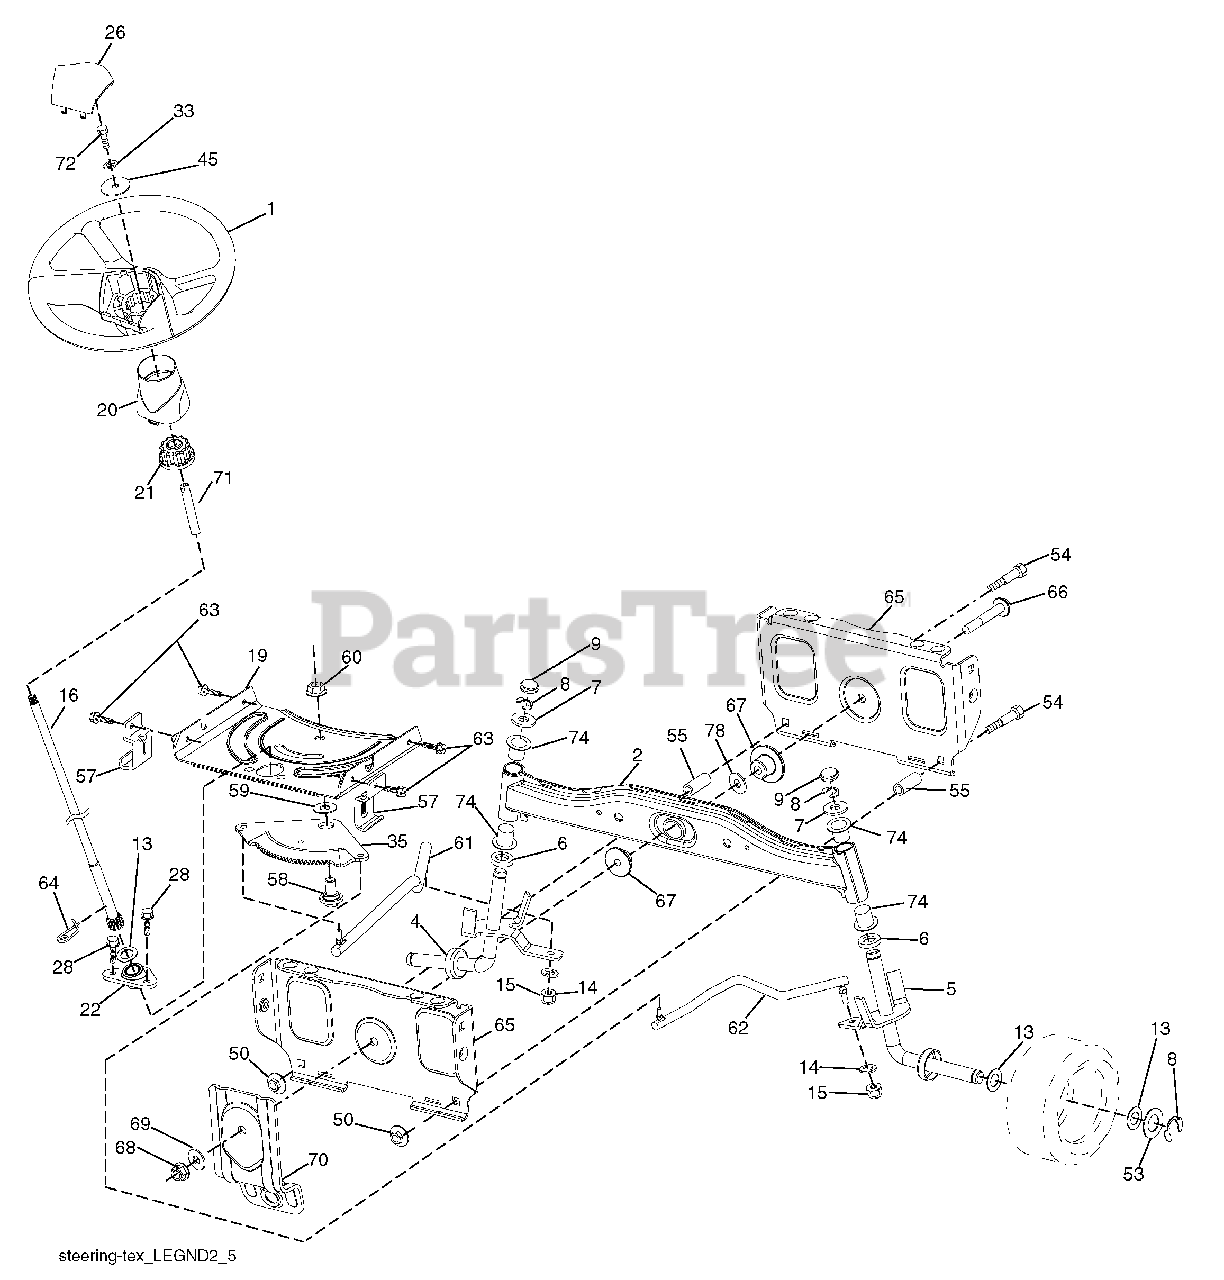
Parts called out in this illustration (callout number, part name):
1	Wheel, Steering
2	Axle Asm. Front
4	Spindle Asm. LH
5	Spindle Asm. RH
6	Bearing, Race Thrust Harden
7	Washer 25/32 x 1-5/8 x 16 Ga.
8	Ring, Clip #T5304-75
9	Cap, Spindle
13	Washer 25/32 x 1-1/4 x 16 Ga.
14	Washer, Lock Hvy. Hlcl. Spr. 3/8
15	Nut, Crown Lock 3/8-24 unf
16	Shaft Steering
19	Plate Steering
20	Boot, Steering
21	Adapter, Wheel Steering
22	Bushing, Strg. Blk.
26	Insert, Wheel Steering
28	Screw 3/8-16 x 3/4
35	Gear, Sector Plate
45	Washer 11/32 ID x 2-3/8 OD x 12 Ga.
50	Nut Lock 3/8-16 unc
51	Nut Hex Jam Toplock 1/2-20 unf
53	Washer Hardened .793 x 1.637 x .060
54	Bolt Hex 3/8-16 unc x 2-1/4
55	Spacer Brace Axle
57	Bracket Upstop
58	Bolt Shoulder Sector Pivot CFM
59	Washer Thrust Sector Steering
60	Nut Flange Lock 5/8-11
61	Draglink LH
62	Draglink, RH
63	Screw 5/16-18 x 3/4
64	Retainer Clip Spring Steering
65	Brace Axle Front
66	Bolt Hex Fghd. 7/16-14 x 3 Serr.
67	Bushing PM Front Axle
68	Nut Lock Flange 7/16-14 Gr. 5
69	Washer 1.5 x .505 x .118
70	Bracket Deck Susp. Front
78	Washer Thrust .515 x .750 x .033
